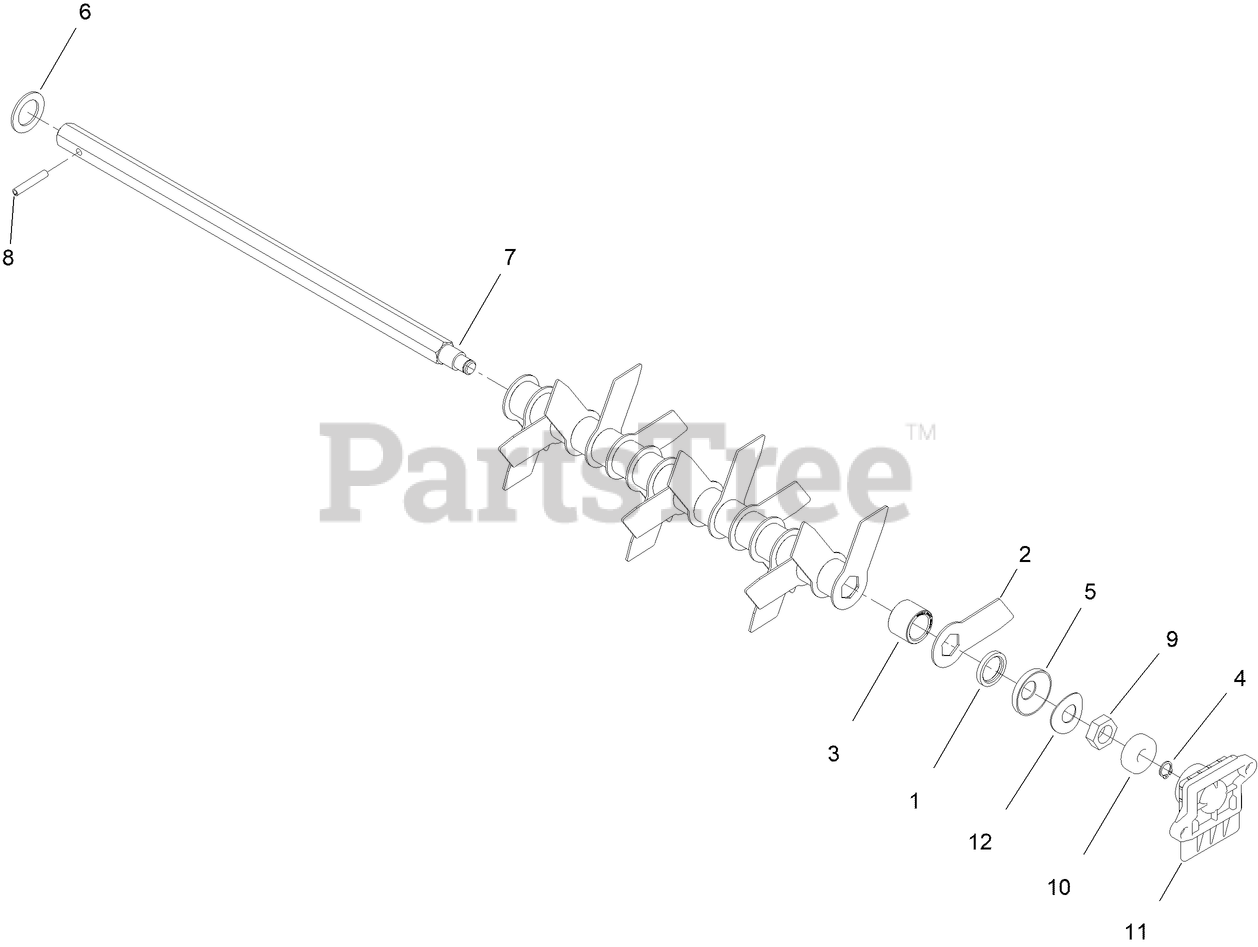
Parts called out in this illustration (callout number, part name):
1	SPACER
2	BLADE-SCARIFIER
3	SPACER
4	CIRCLIP
5	SHOULDER PIECE
6	WASHER
7	ROD-HEX
8	PIN-DOWEL
9	NUT-HEX
10	BEARING
11	BEARING HOUSING V2
12	WASHER-WAVE
